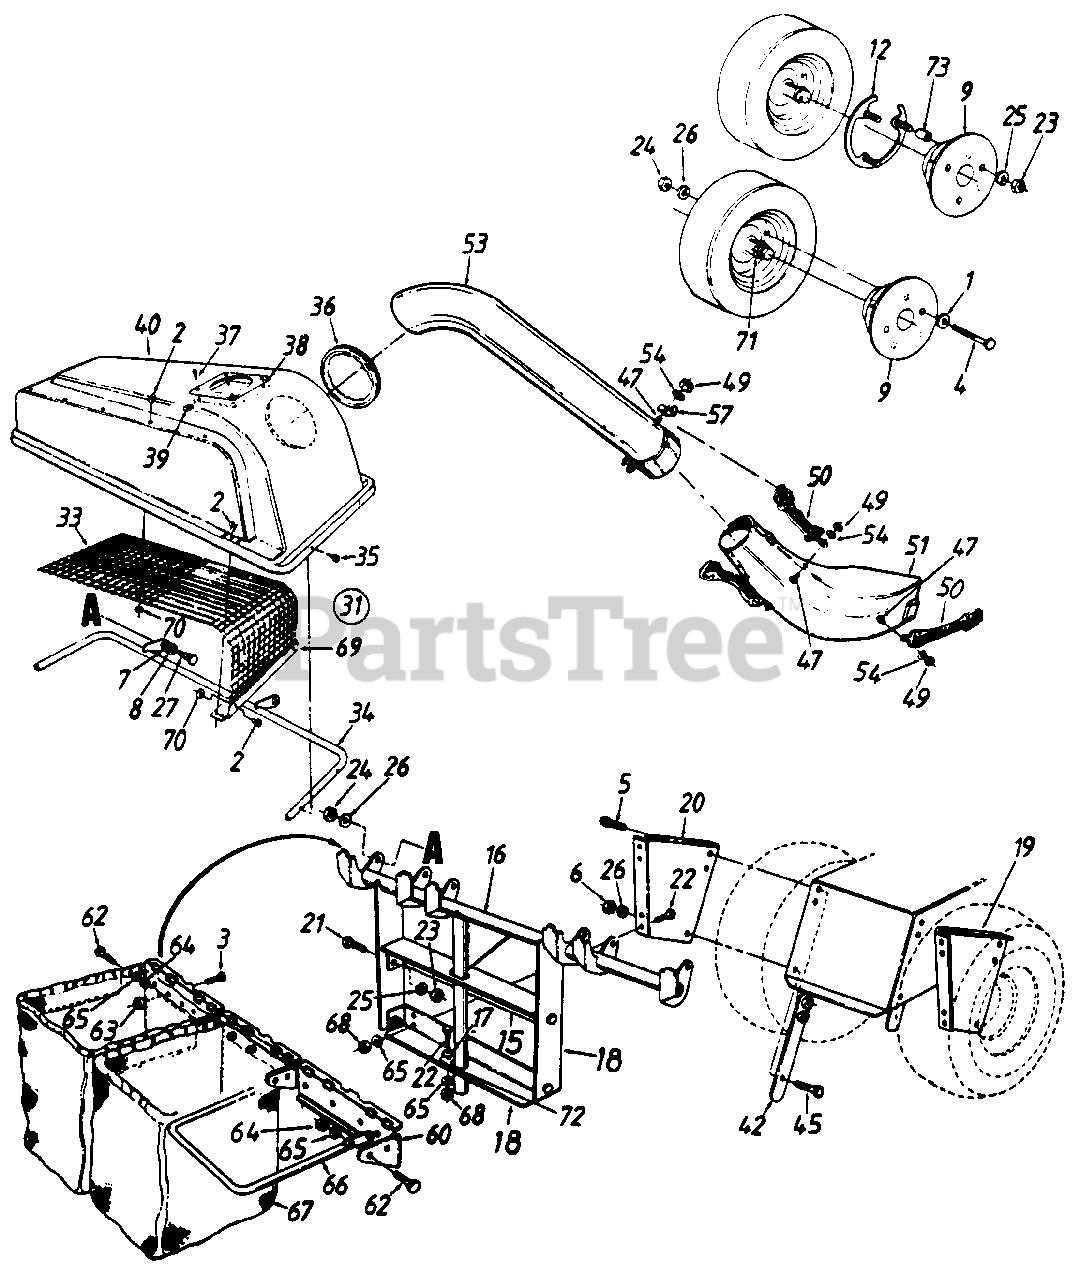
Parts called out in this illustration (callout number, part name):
1	Fl-Wash. .385" I.D.
2	Pop Rivet
3	Truss Mach. Scr. #10-24 x .38" Lg.
4	Hex Bolt 3/8-16 x 4.5" Lg.
5	Hex Wash. Hd. Tap Scr. 5/16 18 x .62"
6	Hex Nut 3/8 24 Thd.
7	Bell Wash . . 515" I.D.
8	FI Wash. .510" I.D.
9	Wheel Weight
12	Wheel Weight Snap Ring
15	Catcher Support Tube Mtg. Brkt.
18	Catcher Latch and Support Brkt.
22	Hex Bolt 1/4-20 x .62" Lg.* Grade 5
23	Hex Nut 5/16-18 Thd.
24	Hex Nut 3/8-6 Thd.
25	L-Wash. 5/16" I.D.
26	L-Wash. 3/8" I.D.
27	Shld. Bolt 3/8-16 x .500" Dia.
31	Grass Catcher Cover Ass'y. Comp.
33	Screen
36	Tube Seal
37	Truss Mach. B-Tap Scr. #10 x.51" Lg.
38	Plastic Plate
39	Speed Nut
40	Grass Catcher Cover
47	Hex Bolt 1/4-20 x .50" Lg.
49	Hex Ins. L Nut 1/20 Thd.
50	Retainer Strap Ass'y.
51	Discharge Chute
53	Catcher Elbow Tube
54	L-Wash. .270" I.D. x 57" O.D.
57	Retainer Hook Brkt.
62	Hex Bolt 1/ 28 x .75" Lg.
63	Hex Sems Nut #10-24 Thd.
64	Hex Nut 1/4-28 Thd.
65	L-Wash. l/4" I.D.
66	Catcher Bag Frame
67	Grass Catcher Bag
68	Hex Nut 1/4-20 Thd.
71	Foam Strip 1-1/8" x 1 1/2" x 3/8"
73	Spacer
